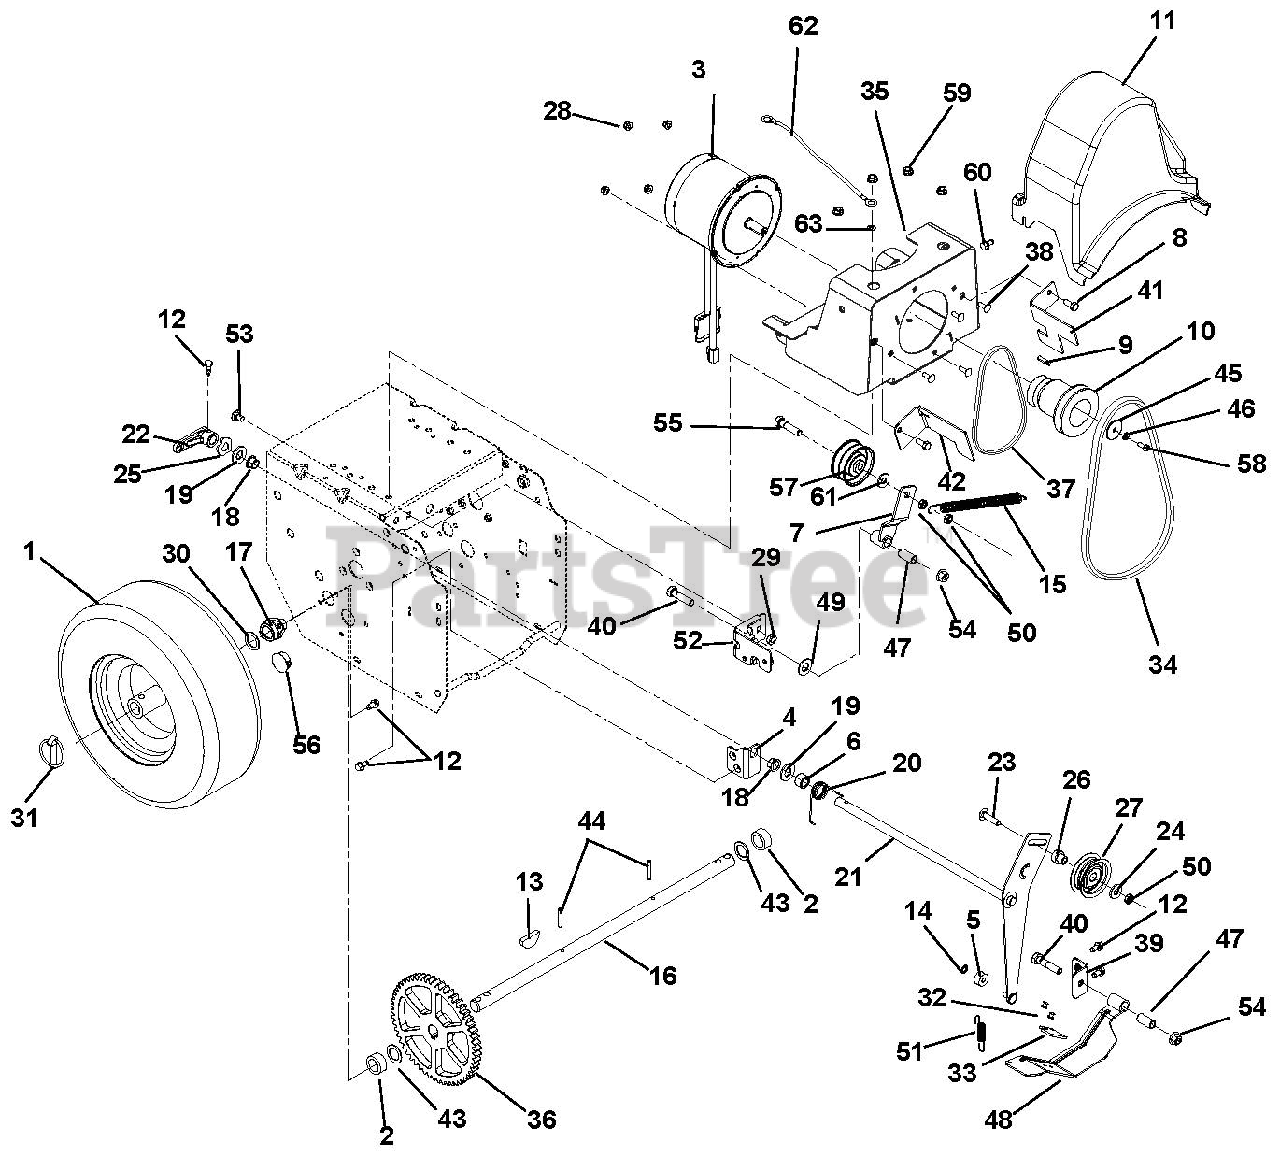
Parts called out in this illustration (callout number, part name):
1	TIRE/WHEEL, RH 4.10-6 PIN K478
1	TIRE/WHEEL, LH 4.10-6 PIN K478
1	TIRE, 4.10-6 K478
2	BSHG-SLV .766 X 1.125 X .500
3	MOTOR, 4 HP ELECTRIC BRUSHLESS
4	BRACKET, MOUNT - IDLER ARM
5	BSHG,SLV .265 X .625 X .375
6	BSHG-SLV .510X.751X.475
7	WELDMENT, TRACTION IDLER ARM
8	@BLT-HEX .31-18X.75 GR5 YWZC
9	KEY-STR 5MMX25MMX5MM
10	SHEAVE, ELECTRIC MOTOR
11	COVER, COMPACT BELT
12	SCR-TAP .25-20X.50 HWH TR YWZ
13	KEY-WDRF .25X.750X.313 SAE91
14	RG-RTNG-EXT .250X.010
15	SG-TENS .062X.56X8.0 WLD 11
16	SHAFT, AXLE
17	BSHG .75X1.125X.65
18	BUSHING, POLYLINER-.50 SPLIT
19	@WSHR-FL-STL.531X1.06X.095YWZC
20	SG-TORS .075 X .955
21	WELDMENT, ATTACHMENT IDLER ARM
22	ARM, CLUTCH - ATTACHMENT
23	BLT-RDHDSQSHNK.31-18X1.13 G5YZ
24	@WSHR-FL-STL.38X.875X.083 YWZC
25	WSHR-WAVE .50X.75X.015 .13FRHT
26	SPCR, BRG .315X.50X.688X.281
27	IDLER
28	@NUT-LK-TOP-FLG .25-20 YWZC
29	@NUT-LK-TOP-FLG .31-18 YWZC
30	WSHR-FL-STL.754X1.125X.062YWZC
31	PIN-LOK .31X1.75
32	RVT-POP .187 YZ
33	PAD, BRAKE
34	V-BELT, HA-RAW EDGE
35	WMT, BATTERY/MOTOR SUPPORT
36	SPUR GEAR, 54T .75ID X 6.75PD
37	V-BELT, 3L-WRAPPED
38	@BLT-RDHDSQNK .25-20X.75 G5YZ
39	BRACKET, MOUNT - BRAKE
40	@BLT-HEX .38-16X1.75 GR5 YWZC
41	FINGER, LH BELT
42	FINGER, RH BELT
43	WSHR-FL-STL.754X1.125X.062YWZC
44	PIN-ROLL .188X1.25
45	WSHR-FL-STL .265X1.370X.179
46	@WSHR-LK .25X.062 REG YWZC
47	BSHG-SLV .385X.500X1.045
48	BRAKE ARM W/PAD
49	@WSHR-FL-STL.406X.812X.065 YWZ
50	@NUT-LK-CTR-JAM .31-18 YWZC
51	SPRING-EXT .437 X .438 X 2.64
52	WELDMENT, FRAME BRACKET
53	@BLT-RHDSSQNK .31-18X.62 G5YZ
54	@NUT-LK-TOP-FLG .38-16 YWZC
55	@BLT-HEX .31-18X1.75 GR5 YWZC
56	PLUG, HOLE - 1.00" FLEXTEMP
57	IDLER,1.875" OD
58	BLT-HEX M6X1.0X25 C10.9 EP80YZ
59	@NUT-LK-TOP-FLG .31-18 YWZC
60	SCR-TAP .25-20X.50 LGHWH TR YZ
61	WSHR-FL-STL .344X1.125X.135
62	CABLE-GROUND .25 X 13.00 X .31
63	WSHR-LOCK INT .31 YWZC
